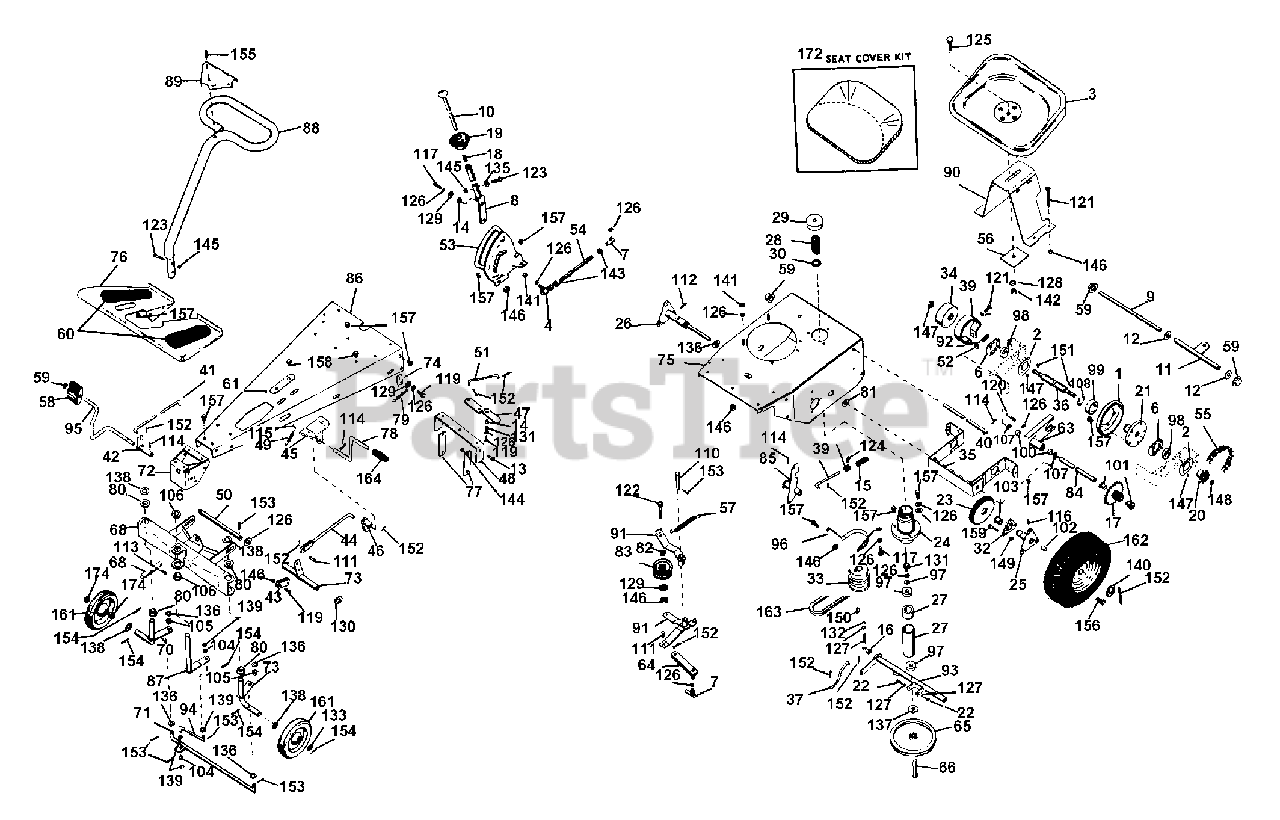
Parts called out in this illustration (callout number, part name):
1	FRICTION DISC
2	BEARING FLANGE
3	MOWER SEAT
4	SNAP IN BALL JOINT
5	SET COLLAR
6	BEARING FLANGE
7	BALL JOINT
8	SHIFT LEVER
9	HITCH SHAFT
10	SHIFT RELEASE HANDLE
12	WAVE WASHER .531X.781X.125FH
13	SHOULDER BOLT .50 X .281
14	SPACER BUSHING .5 X .32 X .21
15	BRAKE SPRING
16	FORK SPACER
17	PINION & SPROCKET
18	SPRING
19	SHIFT BALL
20	9 TOOTH SPROCKET
21	FRICTION DISC HUB
22	SCREW PIN
23	Differential Assembly
24	DRIVE SPRING HOUSING
25	L H AXLE
26	R H AXLE
27	DRIVE SPINDLE HOUSING
28	SPRING
30	SPRING RETAINER
31	AXLE PIVOT PIN
32	SUPPORT, BEARING
33	ENGINE SHEAVE
34	BRAKE DRUM
35	CARRIER
36	HEX SHAFT
38	BRAKE ROD
39	BRAKE BAND
40	DISC FORK ROD
41	FRONT CLTCH ROD
43	FRONT LINK
44	MOWER CLTCH LINK
45	MOWER CLUTCH BRACKET
46	MOWER OVERCENTER LEVER
47	CLTCH TRANSFER LEVER
48	HANGER BRACKET
49	SPRING
50	HANGER PIN
51	REAR CLTCH ROD
52	BRAKE BAND WASHER
53	SHIFT CNTL
54	SHIFT LINKS
55	CHAIN
56	SEAT SUPPORT WASHER
57	IDLER SPRING
59	CAP, .50 ROD YWZC
60	FOOT PAD
61	GUIDE PLATE
62	SHIFT TRANSFER LEVER
63	SLIDING FORK
64	SHIFT LINK
65	DRIVE DISK
66	DRIVE SPINDLE
67	BEARING SPACER .87 X .63 X 1.2
68	FRONT AXLE ASSM
69	L H WHEEL SPINDLE
70	R H WHEEL SPINDLE
71	TIE ROD
72	FRONT FRAME ASSM
73	MOWER CLUTCH LEVER
74	BLADE BRAKE
75	REAR FRAME
76	FOOT REST
77	HANGER LINK
78	MOWER CLTCH PEDAL
79	BRAKE RELEASE CHAIN
80	FLANGE BUSHING
81	FLANGE BUSHING
82	SPCR, BRG .315X.50X.688X.281
83	IDLER
84	CARR SHFT
85	BRAKE BELLCRNK
86	FRAME CHANNEL
87	CENTER STEER COLUMN
89	HNDLBR PANEL
90	SEAT BRCKT
91	IDLER ARM
92	SPRING
94	STEERING LINK
96	REAR BELT FINGER
97	BRG-BALL .625X1.375X.44
98	BRG-BALL .500X1.38X.437
99	BRG-BALL 1.25X2.18X.63
100	BSHG-SLV .625X.750X.500
101	BSHG-FLG .625X.750X.500X.875BR
102	BSHG-SLV .562X.625X.625 BRZ
103	BSHG-FLG.875X1X.625X1.250 BR
104	BSHG-FLG .372X.500X.312X.625NY
105	BSHG-FLG.500X.625X.312X.750NY
106	BSHG-FLG.750X1X.375X1.250 IC
107	SEAL .625X.875X.125
108	RG-RTNG-EXT 1.250X.050
110	PIN-CLEVIS .500 X 3.250
111	CLEVIS PIN
112	PIN-ROLL .188X1.25
113	PIN-ROLL .250X1.25
114	PIN-ROLL .250X1.25
115	PIN-GRV .188X.75 TP G
116	HYDRAULIC DRIVE FITTING
117	BLT-HEX .31-18X1.00 PL GR 2
118	BLT-HEX .25-20X.75 PL GR2
119	BLT-HEX .31-18X.63 PL GR 2
120	BLT-HEX .31-18X1.00 PL GR 2
121	BLT-HEX .31-18X1.00 PL GR 2
122	BLT-HEX .38-16X1.50 PL GR2
123	BLT-HEX .44-14X1.25 PL GR2
124	SCR-SET .25-20X.50 SQHCUP HT
125	BLT-RDHDSQNK .50-13X1.25 PL
126	WSHR-LK .312X.097 PL HVY
127	WSHR-LK .375X.115 HVY PL
128	WSHR-LK .500X.151 HVY PL
129	WSHR-FL-STL .38X.875X.083 PL
130	WSHR-FL-STL .531X1.062X.095 PL
131	BRG-CUP1.980X.420
132	WSHR-FL-STL .38X.875X.083 PL
133	WSHR-FL-STL .531X1.062X.095 PL
134	WSHR-FL-STL .531X1.062X.095 PL
135	WSHR-FL-STL .531X1.062X.095 PL
136	BRG-NEEDLE .625X.812X.50
137	BRG-BALL .625X1.375X.44
138	BRG-CUP 3.346X.532
139	WSHR-FL-STL .812X2.000X.148
140	WSHR-FL-STL .812X2.000X.148
141	NUT-JAM .375-16 PL
142	NUT-JAM .625-11
143	NUT-HEX .312-24 PL
144	NUT-LK-CTR .375-16 GR A PL
145	NUT-LK-CTR .250-20 PL
146	NUT-LK .312-18 GR A PL
147	NUT-KEPS 10-24 PL
148	NUT-LK-CTR .50-20 PL
149	NUT-LK-FLG .250-20 PL
150	KEY-WDRF .156X.625X.25 SAE 6
151	KEY-WDRF .188X.875X.375 SAE11
152	PIN-COTR .09X.75 PL
153	PIN-COTR .12X1.0 PL
154	PIN-COTR .09X.75 PL
155	RVT-POP.125 X .294 DOME
156	BRG-CUP 2.441X.562
157	BLT-SERHFWH .31-18X.50 PL
158	BLT-SCRHFWH .38-16X.50 PL
159	SCR-SLTR-SERNK .25-20X.62 PL
160	Special Cap Screw
161	WHL 10 IN O.D.
162	WHL 12.25 IN O.D.
163	V-BELT, SAE 380-RAW EDGE
165	HEIGHT QUADRANT LABEL
166	MOWER IN-OUT LABEL
167	DISCHARGE CAUTION LABEL
168	DISCHARGE CAUTION LABEL
169	DISCHARGE CAUTION LABEL
170	HEIGHT QUADRANT LABEL
171	MOWER IN-OUT LABEL
172	Seat Cover Kit
173	BSHG-FLG.750X1.125X1.000X1.250
174	BSHG-FLG.750X1.125X1.000X1.125
